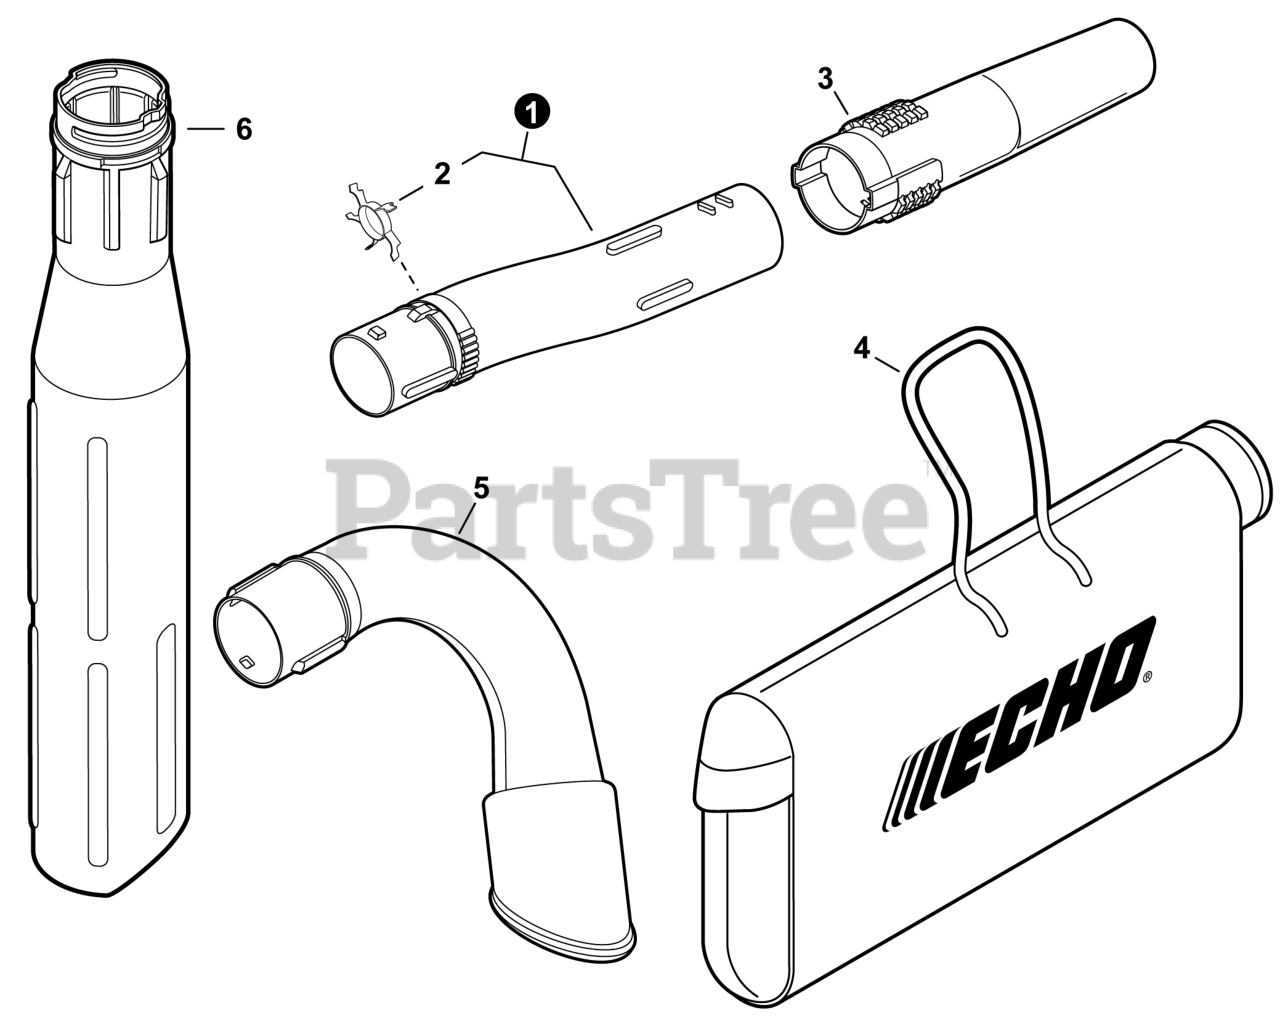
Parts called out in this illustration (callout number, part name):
1	TUBE, BLOWER - CURVED
2	GUARD - BLOWER TUBE
3	TUBE, BLOWER - ROUND NOZZLE
4	BAG, DEBRIS
5	TUBE, BLOWER - ELBOW
6	TUBE, BLOWER - SUCTION
